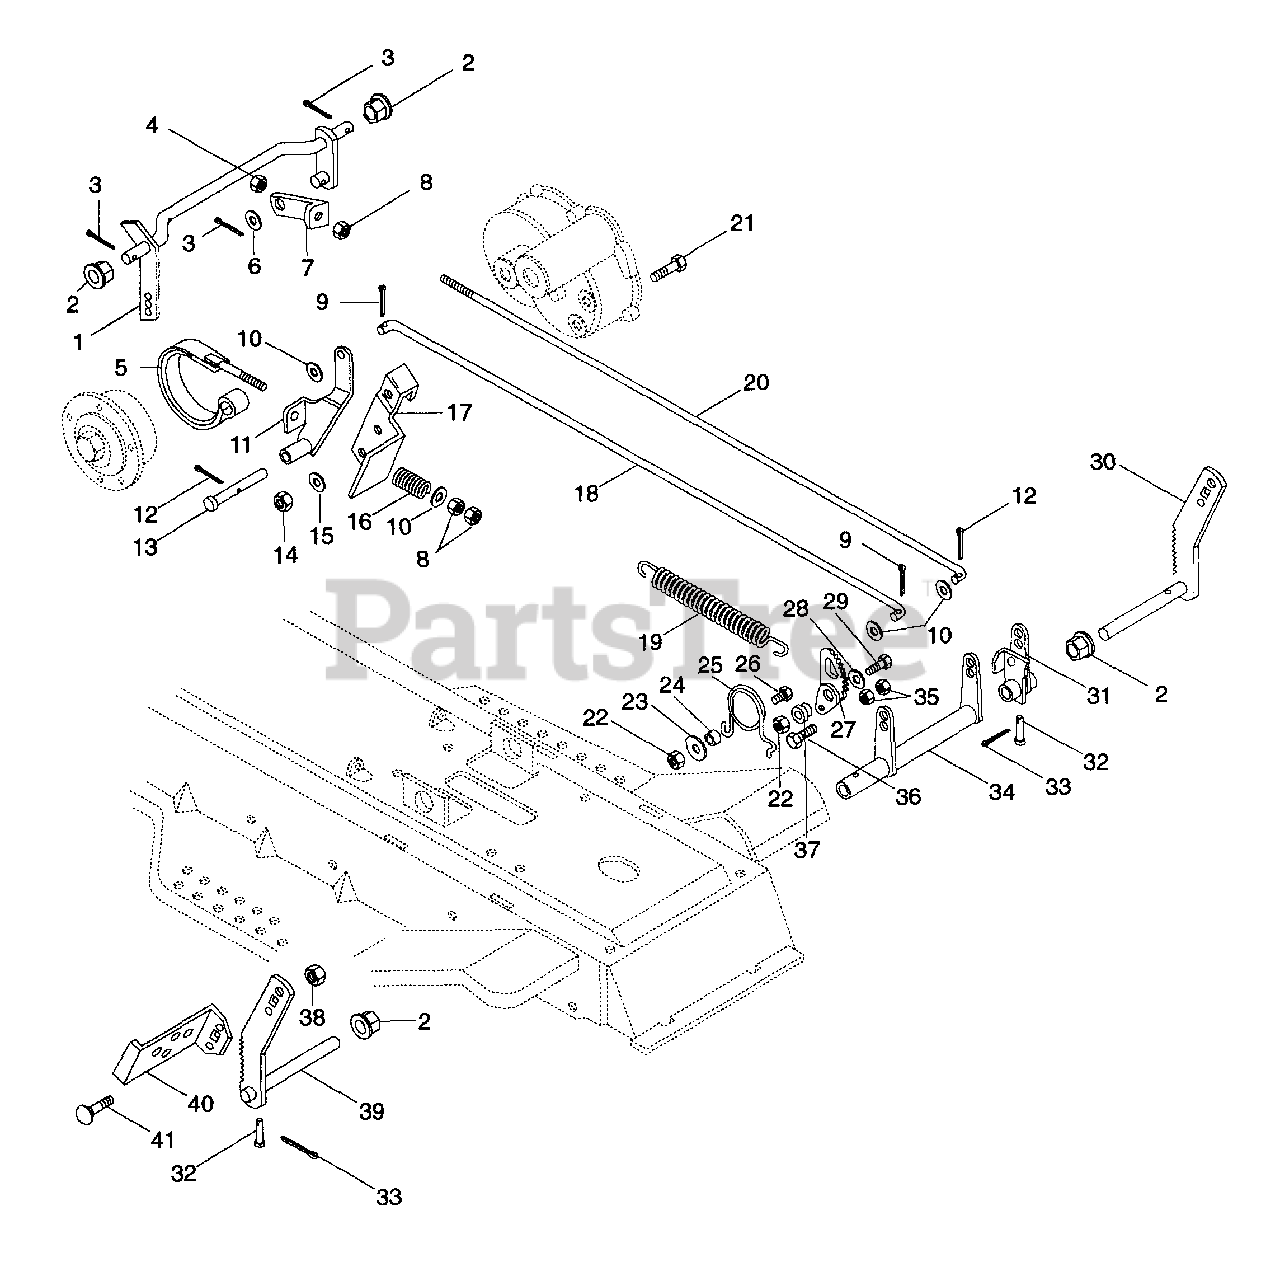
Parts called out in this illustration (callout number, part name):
1	CLUTCH SHAFT
2	FLANGE BUSHING
3	PIN-COTR .12X1.0 PL
4	NUT-LK-NYL.312-18 PL
5	BRAKE BAND
6	WSHR-FL-STL .520X.810X.033
7	CLUTCH BRACKET
8	NUT-HEX .312-18
9	PIN-COTR .09X.75 PL
10	WSHR-FL-STL .323X.625X.062 PL
11	BRAKE LEVER
12	PIN-COTR .12X.75 PL
13	PIN-CLEV .371X3.25
14	NUT-HEAVY .312-18 PL
15	WSHR-LK-INT .313X.030 PL
16	SG-COMP .105X.585X.75
17	BRAKE BRACKET
18	BRAKE ROD
19	SG-TENS .051X.60X2.25 WLD 7.0
20	ROD, CLUTCH
21	BLT-SERRDHD SL .31-18X.75 YZ
22	NUT-LK .312-18 GR A PL
23	WSHR-FL-STL .344X1.125X.063PL
24	SPACER BUSHING .5 X .32 X .163
25	SG-TORS .125X1.0X1.75
26	BLT-HEX .31-18X.63 PL GR 2
27	BRAKE LATCH
28	WSHR-FL-STL .38X.875X.083 PL
29	BLT-HEX .31-18X1.00 PL GR 2
30	CLUTCH PEDAL ARM
31	CLUTCH ARM
32	PIN-CLEV .185X1.00 SP
33	PIN-COTR .06X.50
34	BRAKE ARM
35	NUT 8-32 PL
36	SCR-MCH 8-32X1.00 SLTR PL
37	SPACER -SHLD .344X.500X.469
38	NUT-LK-JAM-CTR .375-16 PL
39	BRAKE PEDAL ARM
41	BLT-RDHDSQNK .38-16X.75 SHT PL
